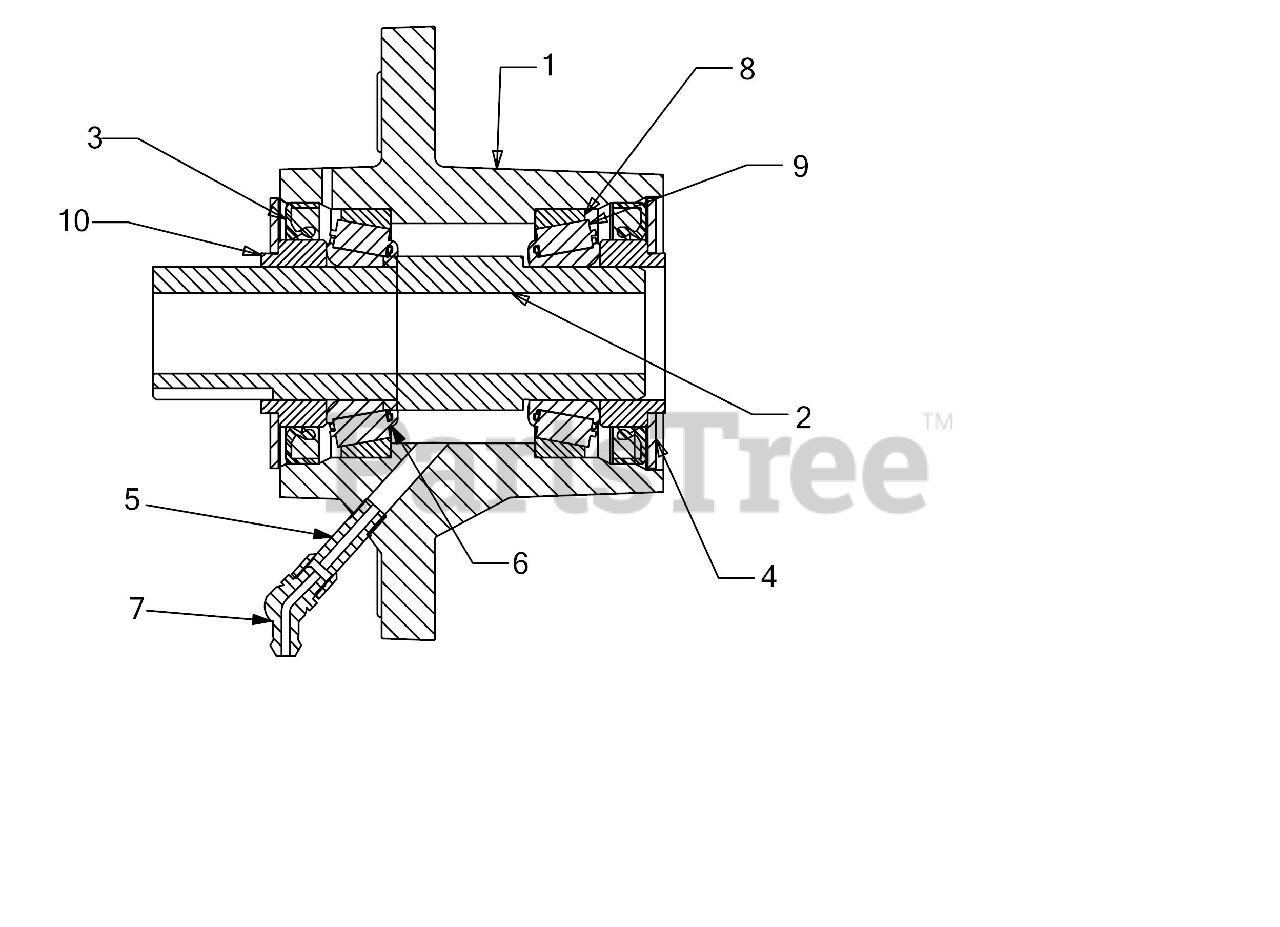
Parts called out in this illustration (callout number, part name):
1	HOUSING
2	SPINDLE SHAFT
4	DUST WASHER
5	FITTING ADAPTER
6	GREASE
7	45 DEGREE LUBE FITTING 1/4-28 TAPER
8	BEARING CUP
9	BEARING CONE
